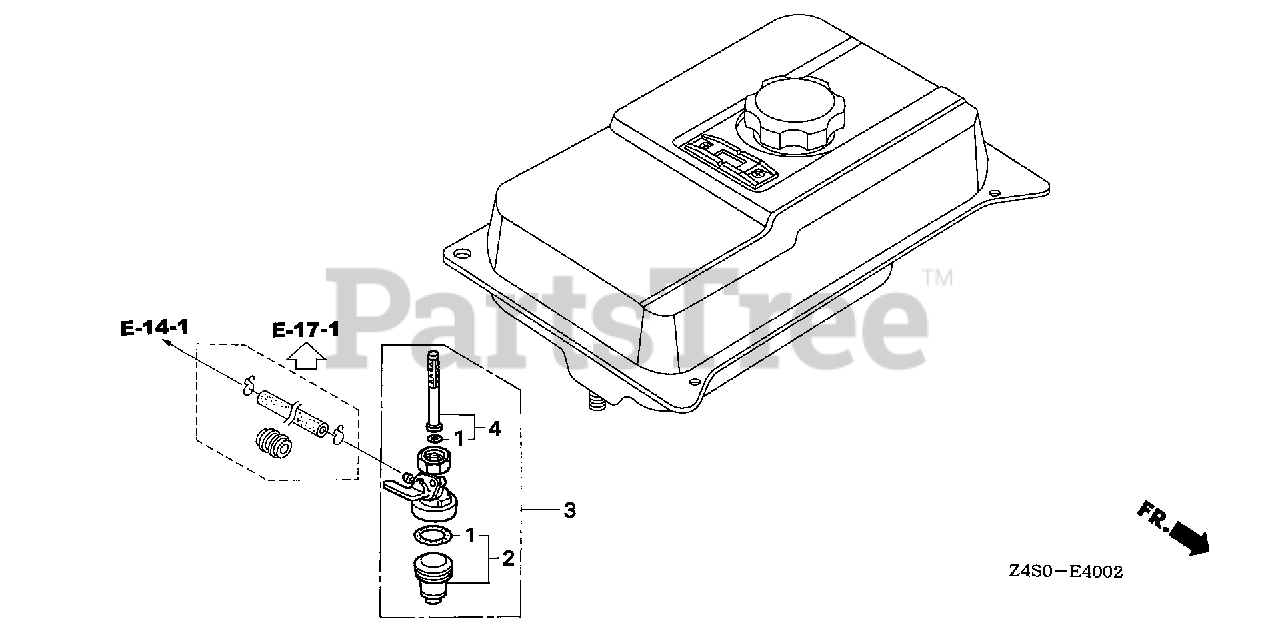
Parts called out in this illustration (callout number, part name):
1	GASKET SET, PETCOCK (CONTAINS 1 LARGE & 1 SMALL. USE AS NEEDED)
2	CUP, FUEL STRAINER
3	PETCOCK ASSY.
4	SCREEN SET
